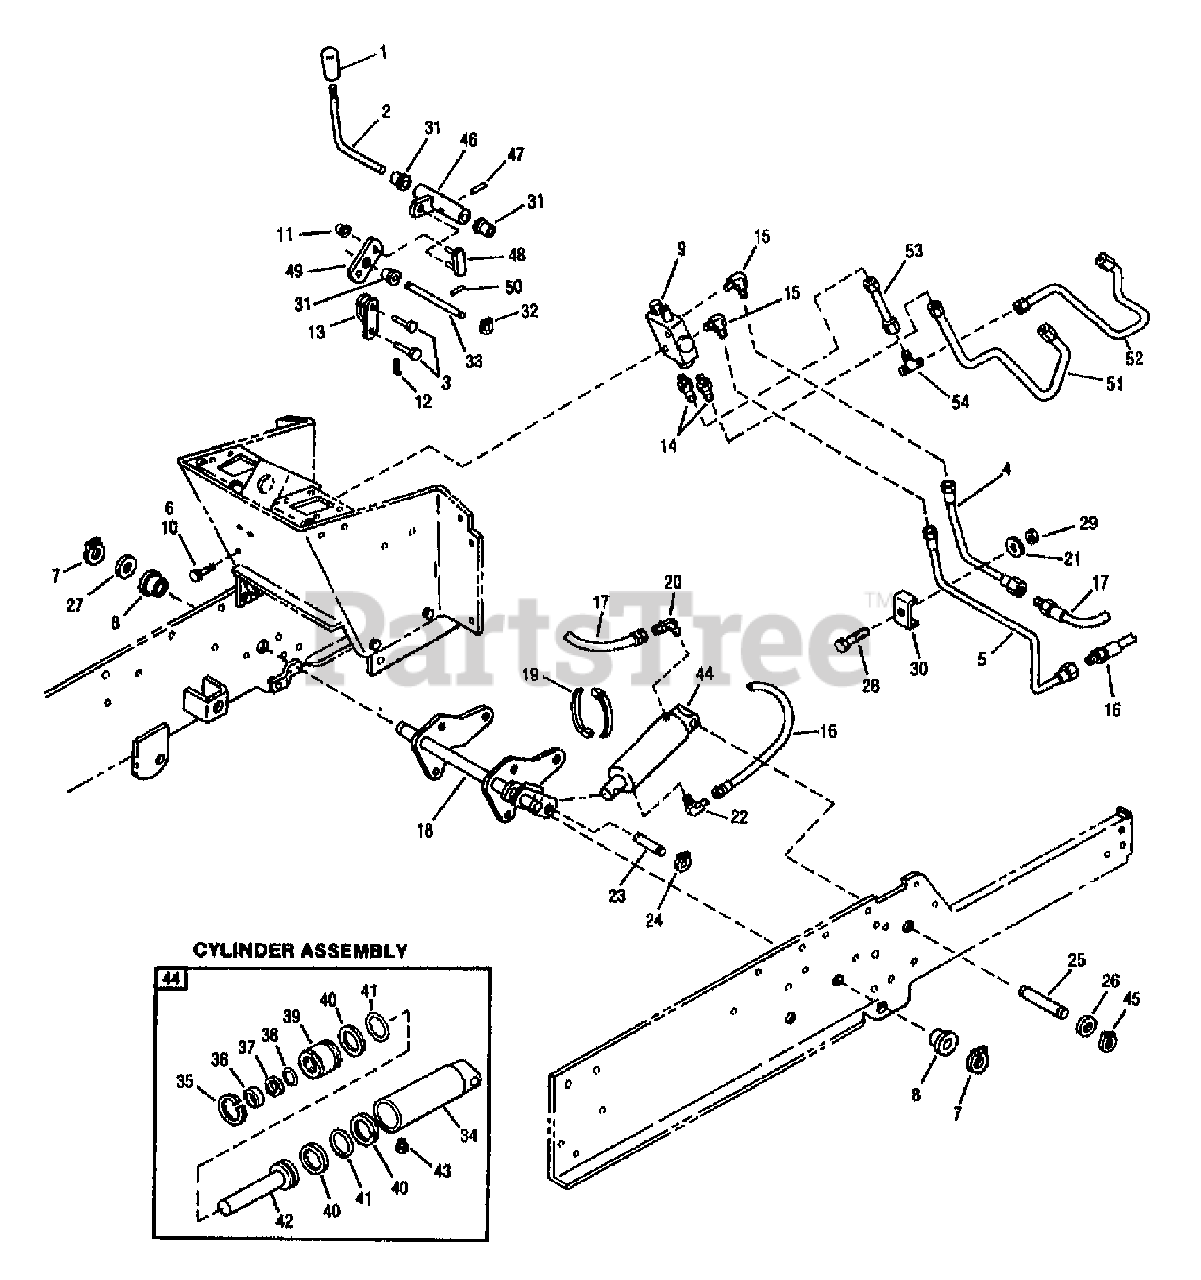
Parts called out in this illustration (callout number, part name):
2	LEVER-CONTROL
3	PIN-CLEVIS .25X.81
4	ASSM-TUBE
5	ASSM-TUBE
6	SCR-HFLK 1/4-20X2.00 G5ZP
7	RING-RETAINING
8	BUSHING-FLANGE
10	NUT-HF/LK 1/4-20 ZP
12	PIN-COTTER
13	ASSM-VALVE LINK
14	CONNECTOR
15	ELBOW
16	ASSM-HOSE
17	ASSM-HOSE
19	TIE-CABLE
20	ELBOW
21	WASHER-FLAT 1.25X.406X.179
22	ELBOW
24	RING-RETAIN .625 ID
26	WASHER-1.5X.755X.062
27	WASHER-SPEC
28	SCR-HH 5/16-18X1.0 G5 ZP
29	NUT-H/LK 5/16-18
30	CLAMP
31	BRG-FLANGE
32	RING-RETAINING
33	PIN-PIVOT
34	ASSM-CYL HYDRAULIC
35	RING-RETAIN INT 2.210 DIA
36	SEAL-OIL
37	RING-BACK/UP
38	RING-O .984 ID
39	HEAD-CYLINDER
40	RING-BACK/UP
41	RING-O 1.6 ID
42	ASSM-ROD HYDR CYLINDER
43	PLUG-PIPE
44	ASSM-CYL HYDRAULIC
45	RING-RETAIN EXT .707 ID
46	ASSM-CONTROL ARM
47	PIN-DRIVE
48	ASSM-CONTROL LINK
49	ARM-ROCKER
50	PIN-ROLL .125 X .62
51	ASSM-TUBE
52	ASSM-TUBE
53	ASSM-TUBE
